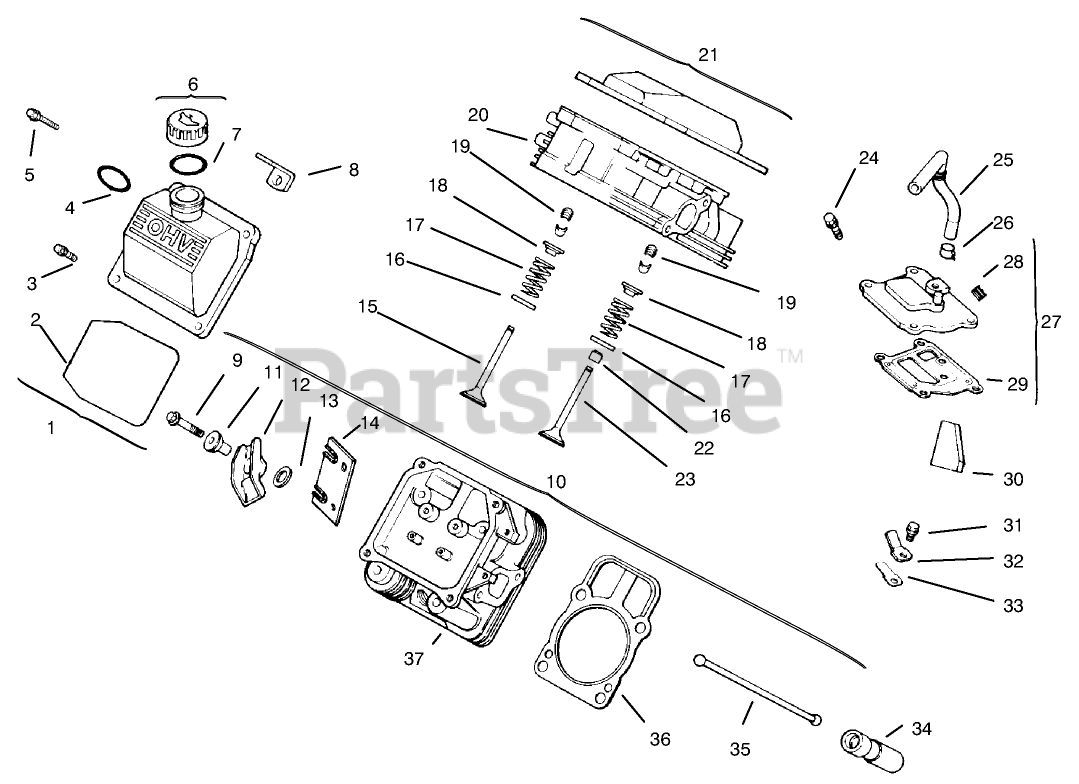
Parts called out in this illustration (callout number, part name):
1	Kit-Valve Cover (Incl. Ref. #2-4)
2	O Ring
3	Screw
4	O-Ring
5	Screw
6	Kit-Oil Fill Cap (Incl. Ref. #7)
7	"O"Ring
8	Strap-Lifting
9	Screw
10	Kit-Valve Train (Incl. Ref. # 11-14 & 35)
11	Pivot-Rocker Arm
12	Arm-Rocker
13	Washer
14	Plate-Guide
15	Valve-Exhaust
16	Retainer-Spring
17	Spring-Valve
18	Cap-Spring, Valve
19	Retainer Kit
20	Head Asm-#1 Cylinder
21	Kit-Valve Cover (Incl. Ref. # 2 & 3)
22	Seal-Stem, Valve
23	Valve-Intake
24	Screw
25	Hose-Breather
26	Clamp
27	Kit-Breather w/Plug (Incl. Ref. # 28 & 29)
28	Plug
29	Gasket-Breather
30	Filter-Breather
31	Screw
32	Retainer-Reed
33	Reed
34	Lifter-Valve
35	Rod-Push
36	Gasket-Cylinder Head
37	Head Asm-#2 cylinder
